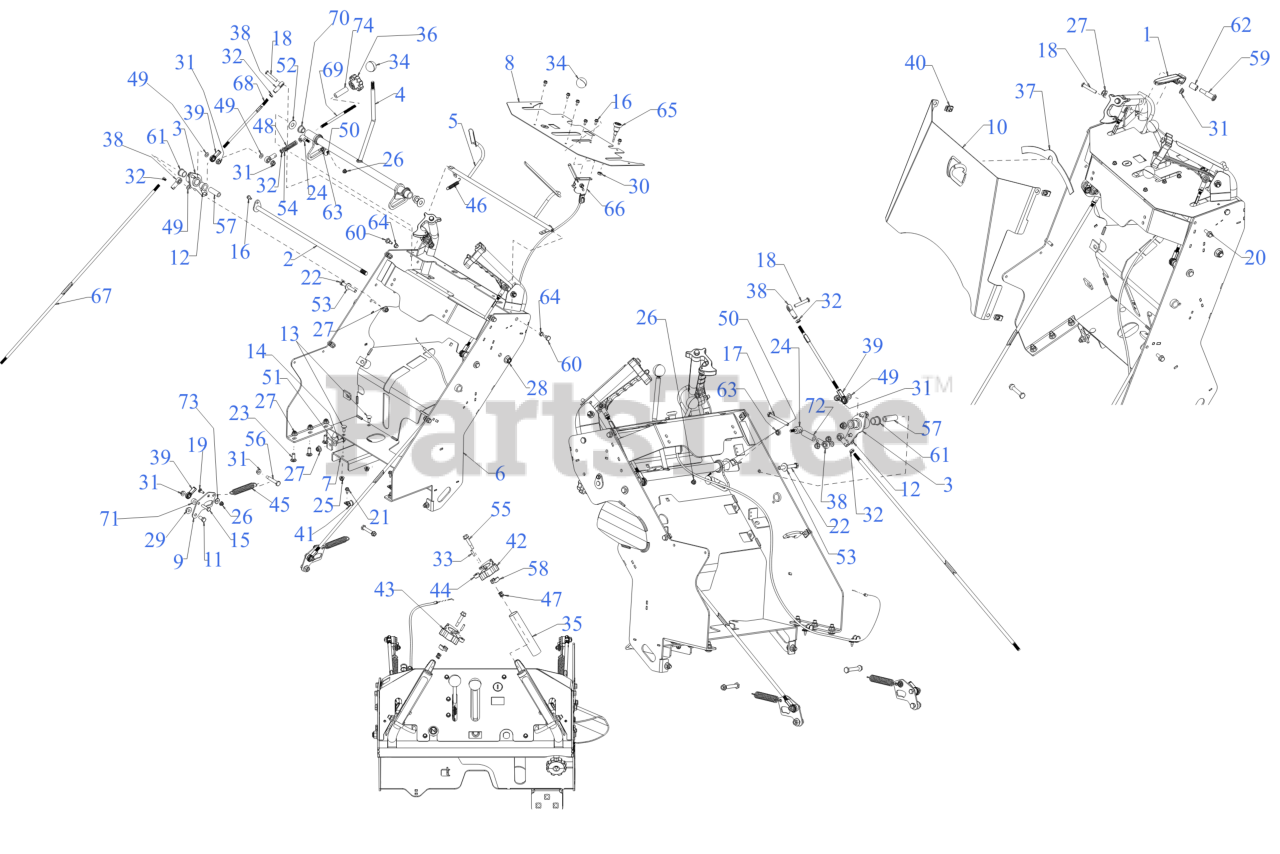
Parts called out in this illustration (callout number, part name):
2	CONTROL PIVOT WELDMENT
3	BELLCRANK ASSEMBLY
4	CRUISE CONTROL ASSEMBLY
6	HANDLE CONTROL ASSEMBLY
8	CONTROL PANEL
11	HEX SCREW 3/8-16 x .75
12	CARRIAGE BOLT 5/16-18 x 1.00
13	CARRIAGE BOLT 5/16-18 x .75
14	SCREW 3/8-16 x 1 GR5
15	SCREW 5/16-18 x 1.25 GR5
16	SCREW 1/4-20 X.500
17	SCREW (5/16-24:3.00:GR5)
18	SCREW (5/16-18:1.7)
19	SCREW 1/4-20 x .75 GR5
20	SCREW 5/16-18 x .875 GR5 HXFLG HD
21	SCREW 1/4-20X.625
22	SCREW 3/8-16 x 2.75 GR5
23	CARRIAGE BOLT 3/8-16 x 1.00 GR5
24	FURRLE (.328 ID x .250)
25	FLANGE LOCK NUT 5/16-18
26	FLANGE LOCK NUT
29	HEX NUT INS L-3/8-16
30	HEX JAM NUT 3/8X24
31	HEX FLANGE NUT
32	NUT-5/16X 24
33	DOWEL PIN
35	GRIP (1.0 ID x 5.5 x .065)
36	KNOB (5/16-24) (LH)
37	BLOWER HOUSING SEAL
38	ROD END 5/16 ID
39	END ROD- 5/16 (LH)
42	HANDLE LOCK (RH)
43	HANDLE LOCK (LH)
44	NEUTRAL LOCK ROLLER
45	EXTENSION SPRING
46	EXTENSION SPRING
47	NEUTRAL LOCK SPRING
48	TRACKING SPRING
49	FLAT WASHER
50	FLAT WASHER
51	FLAT WASHER .401X.88
52	FLAT WASHER (0.526X1.250X0.048)
54	FLAT WASHER ID-.320 x .598
55	SHOULDER SCREW
56	SHOULDER SCREW
57	BELLCRANK SPACER
58	NEUTRAL LOCK SPACER
59	SHOULDER SCREW .50X.925
60	SHOULDER SCREW .375X.380:1/4-20
61	FLANGE BEARING
62	SLEEVE BEARING .623 x .5025 x .250
63	BALL BEARING .25 x .625 SPCL
64	FLANGE BEARING .375X.580X.250
65	CHOKE CABLE
66	THROTTLE CABLE
67	TRANSMISSION CONTROL ROD
68	CONTROL LEVER ROD
69	CONTROL TRACKNG ROD
70	FLANGE BEARING .503ID
71	IDLER BRACKET SPACER .340X.750X.330
72	SPACER (.322 x .625 x 1.8)
73	TRANSMISSION SPACER
